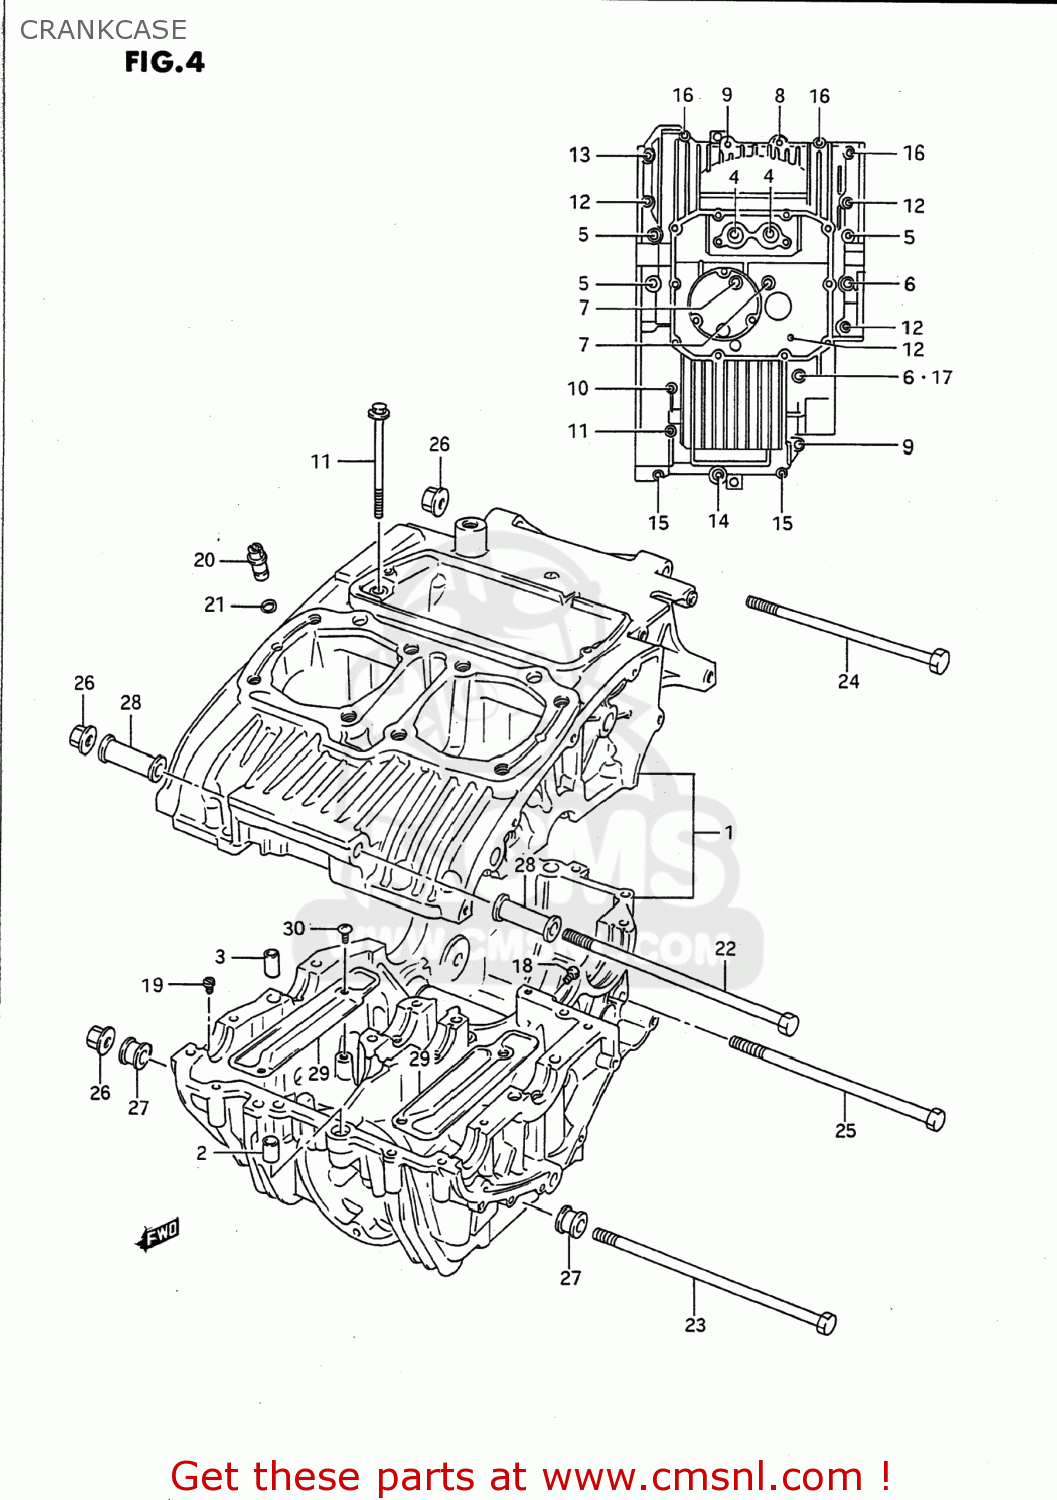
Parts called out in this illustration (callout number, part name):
1	CRANKCASE SET
2	PIN(10.4X13X22)
3	PIN (11X20)(SUS)
4	BOLT
5	BOLT(8X125)
6	BOLT
7	BOLT(8X100)
8	BOLT
9	BOLT
10	BOLT(6X125)
11	BOLT(6X105)
12	BOLT (6X90)
13	BOLT
14	BOLT
15	BOLT
16	BOLT (6X45)
17	GASKET 8.2X14X1 (NAS)
18	JET,AIR
19	JET
20	JET
21	O RING(D:1.05,ID:3.1)
22	BOLT(10X255)
23	BOLT(10X240)
24	BOLT(10X170)
25	BOLT
26	NUT
27	SPACER,ENG MTG(L:16.8)
28	SPACER,ENGINE MOUNT(L:65)
29	PLATE,OIL SEPARATOR
30	SCREW
